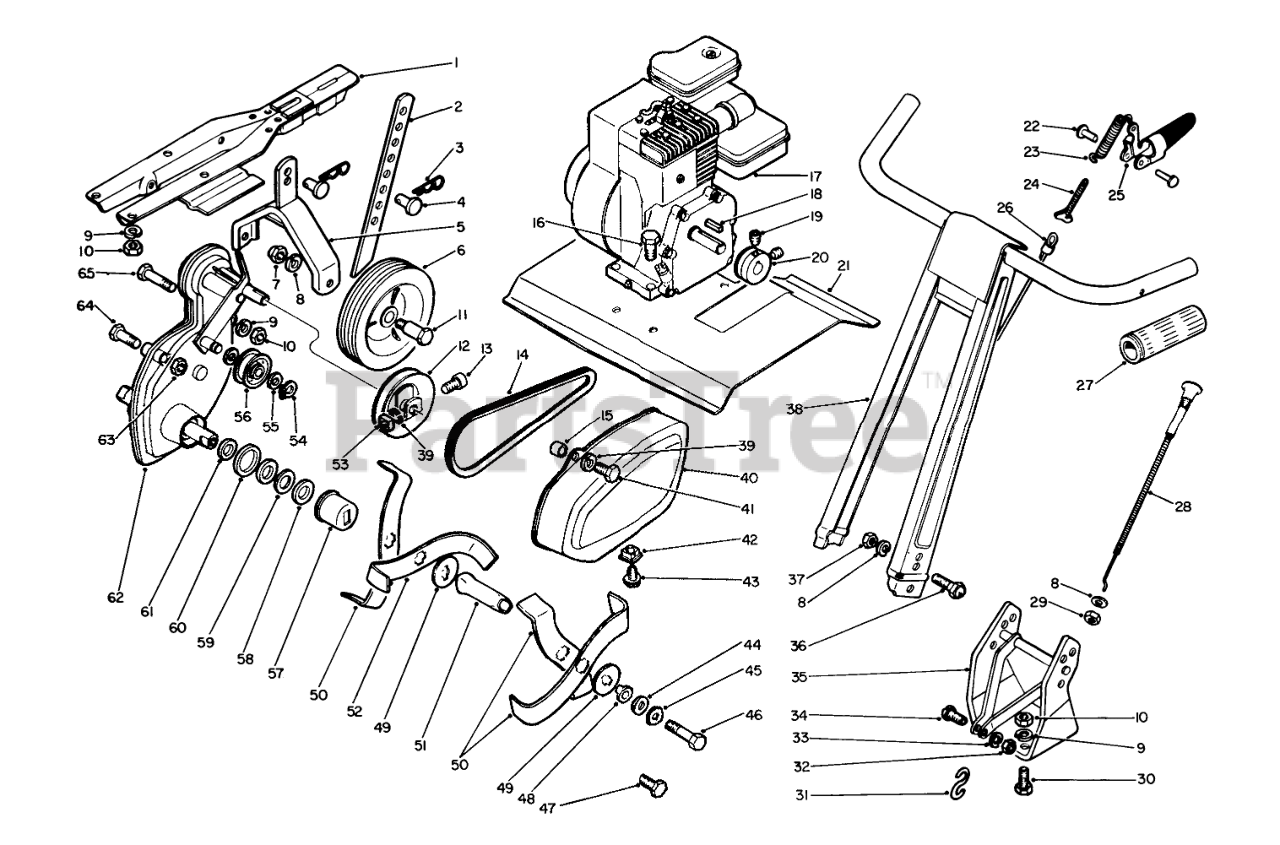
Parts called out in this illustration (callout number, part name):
1	Frame
2	Depth Stick
3	Spring Clip
4	Clevis Pin
5	Wheel Hanger
6	Wheel & Tire Assembly
7	NUT-LOCK, CONE
8	WASHER-LOCK
9	WASHER-LOCK
10	NUT-HEX
11	Shoulder Bolt
12	Pulley Assembly
13	Socket Hd. Capscrew
14	V-BELT
15	Spacer
16	SCREW-HH
17	Engine
18	KEY-SQUARE
19	SCREW-SET
20	Engine Pulley
21	Tine Shield
22	Rivet Assembly
23	Spring-Adjuster
24	Stud-Adjustment
25	Clutch Grip
26	Clutch Cable Assembly
27	Grip
28	Throttle Control
29	NUT-HEX
30	SCREW-HH
31	-S- Hook
32	NUT-LOCK, SIDE
33	WASHER-LOCK
34	Machine Screw
35	Support-Handle
36	Acorn Hd. Bolt
37	NUT-HEX
38	Handle W/Decal
39	WASHER-LOCK
40	Belt Guard W/Decal
41	SCREW-HH
42	Expansion Nut
43	Hex Hd. Tapping Screw
44	Washer
45	LOCKWASHER
46	Tine Bolt
47	SCREW-HH
48	Bushing
49	Washer
50	Tine R.H.
51	Tine Extension
52	Tine L.H.
53	NUT-SQUARE
54	RING-SNAP, EXTERNAL
55	Washer
56	Idler Pulley
57	Seal Collar Assembly
58	Felt Seal
59	Washer
60	Felt Seal
61	Seal
62	Chain Case Assembly
63	NUT-LOCK, CONE
64	SCREW-HH
65	SCREW-HH
